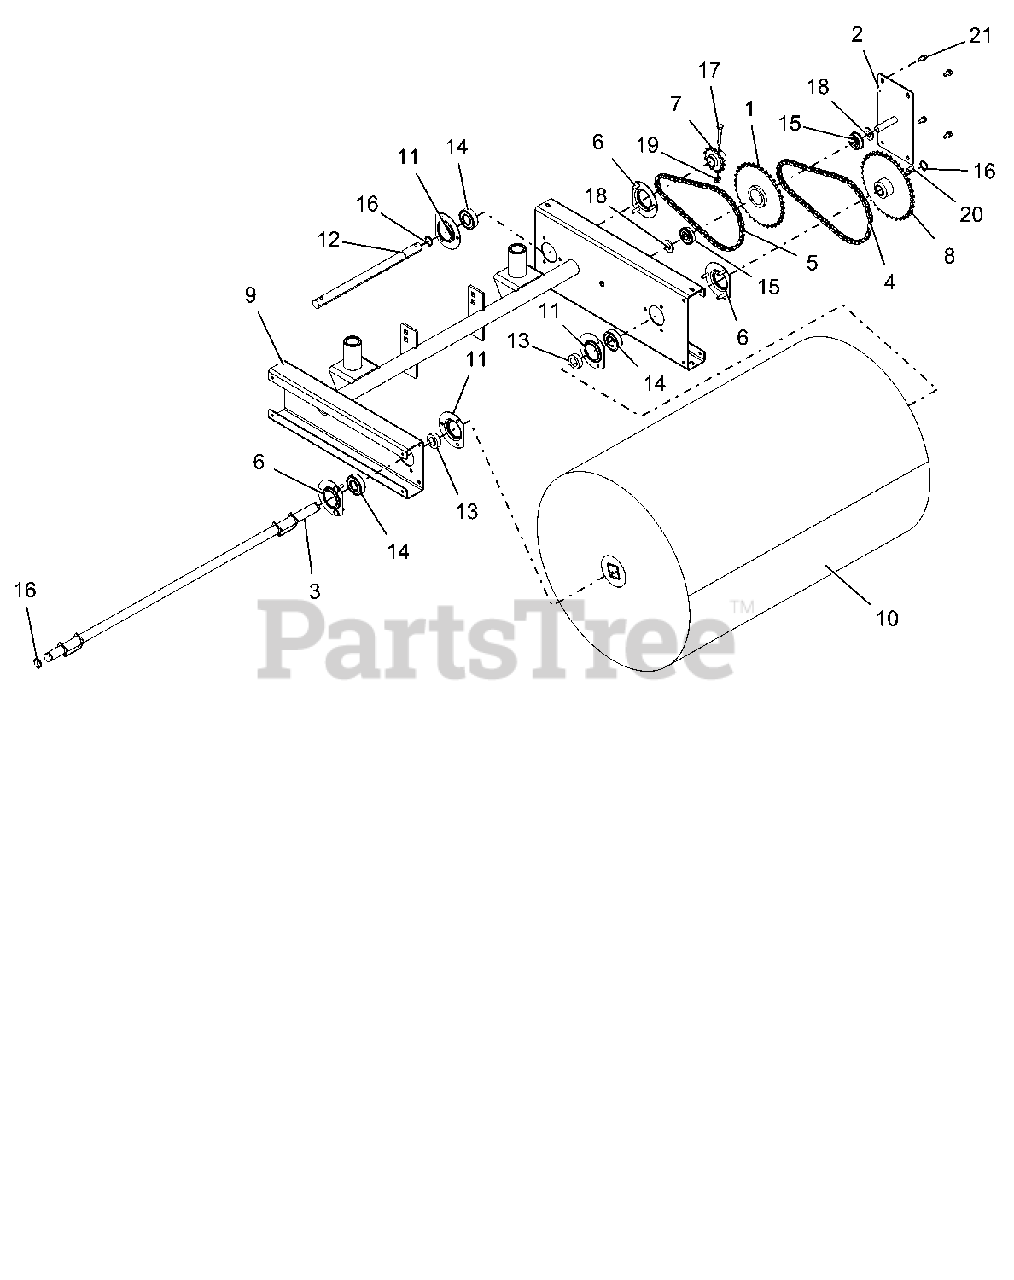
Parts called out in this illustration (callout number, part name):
1	SPROCKET, REDUCTION IDLER
2	MOUNT, REDUCTION IDLER (RED)
3	SHAFT, 28" BRUSH
4	CHAIN, #40-54 LINKS
5	CHAIN, #41-50 LINKS
6	FLANGE, BEARING
7	SPROCKET, DRIVE
8	SPROCKET, DRIVEN
9	FRAME, POWER BROOM-DELUXE (BLACK)
10	BRUSH, 18" DIA X 28" WIDE
11	FLANGE, BEARING
12	SHAFT, TRANSMISSION
13	SPACER, .755x1.250x.370
14	BRG-BALL .750X1.750X.50
15	BRG, BALL .501 X 1.38 X .438 SEALED
16	RG-RTNG-EXT .750x.078
17	BLT-HEX .25-20X1.75 GR5 YWZC
18	WSHR-FL-STL .536X1.070X.109 YWZC
19	NUT, LK-TOP-FLG .25-20 YWZC
20	KEY, WDRF - .188X.75X.313 REV
21	SCR-TAP .25-20X.50 HWH TR YWZ
